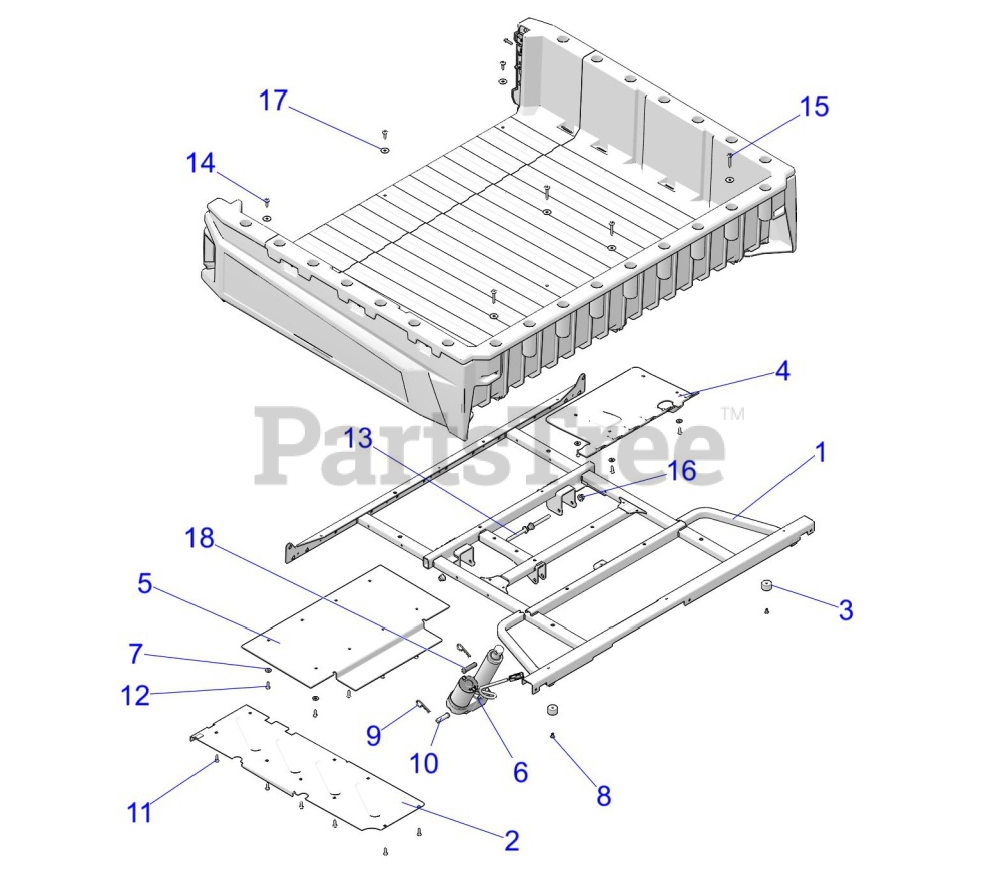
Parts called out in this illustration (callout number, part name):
1	WELD-FRAME,BOX,BLK
2	SHIELD-BOX,CARGO
3	BUMPER-BOX
4	SHIELD-HEAT,FOIL,BOX,RGR
5	SHIELD-HEAT,EXHAUST,REAR
6	ACTUATOR,BOX LIFT,CMPT,TTN
7	WASHER-.312 X .734 X .065-Z
8	RIVET(50)
9	CLIP, HITCH PIN
10	PIN, CLEVIS
11	SCR-TXPH-#14 X .75 HI-LO RIE
12	SCR-TXPH-#14X3/4 HI/LO CLR
13	SCR-HXFL-M10X1.25X80 8.8 ZOD
14	SCR-TXTH-M6X1.0X25 RIE
15	SCR-TXTH-M6X1.0X45 RIE
16	NUT-M10X1.25,FLG,NYLOC-OLIVE D
17	WASHER-.281X1.00X.051
18	PIN, CLEVIS BOX LIFT 2"
